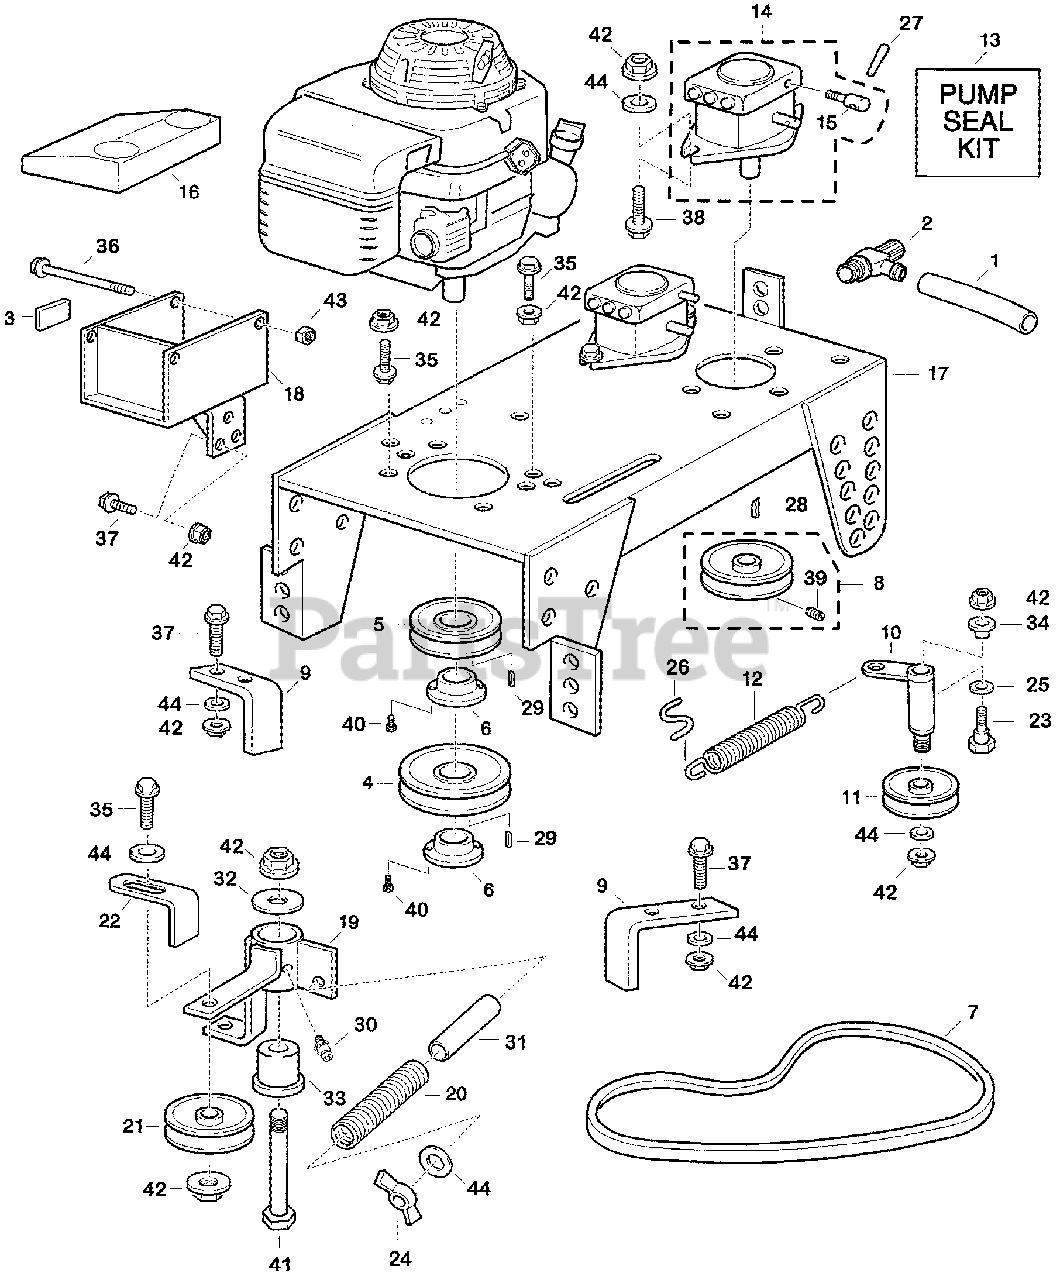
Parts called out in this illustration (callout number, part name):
1	TUBE, OIL DRAIN
2	VALVE, OIL SHUT-OFF
4	PULLEY, DRIVE
5	PULLEY, PUMP DRIVE
6	BUSHING, SPLIT (1")
7	V-BELT, ENGINE PUMP
9	STOPPER, BELT
10	BELLCRANK, IDLER
11	PULLEY, IDLER
12	SPRING, TENSIONER
13	SEAL KIT, PUMP
14	PUMP ASSY., HYDRAULIC
15	VALVE, PUMP BYPASS (KIT)
17	BED, ENGINE
19	ARM, TENSIONER
20	SPRING, TENSIONER ARM
21	PULLEY A, TENSION
22	GUIDE A, BELT
23	BOLT A, SHOULDER
24	WINGNUT (5/16"-18)
25	WASHER, BELLEVILLE (1/2")
26	CLIP, SPRING
27	PIN, TAPERED
28	KEY, SQUARE (5X5X28)
29	KEY, SQUARE (1/4"X1/4"X1")
30	NIPPLE, GREASE
31	TUBE, VINYL (7/16"X2) (1/2")
32	WASHER (1" MACH)
32	BUSHING (1")
33	BUSHING, PIVOT
34	BUSHING, SNAP
